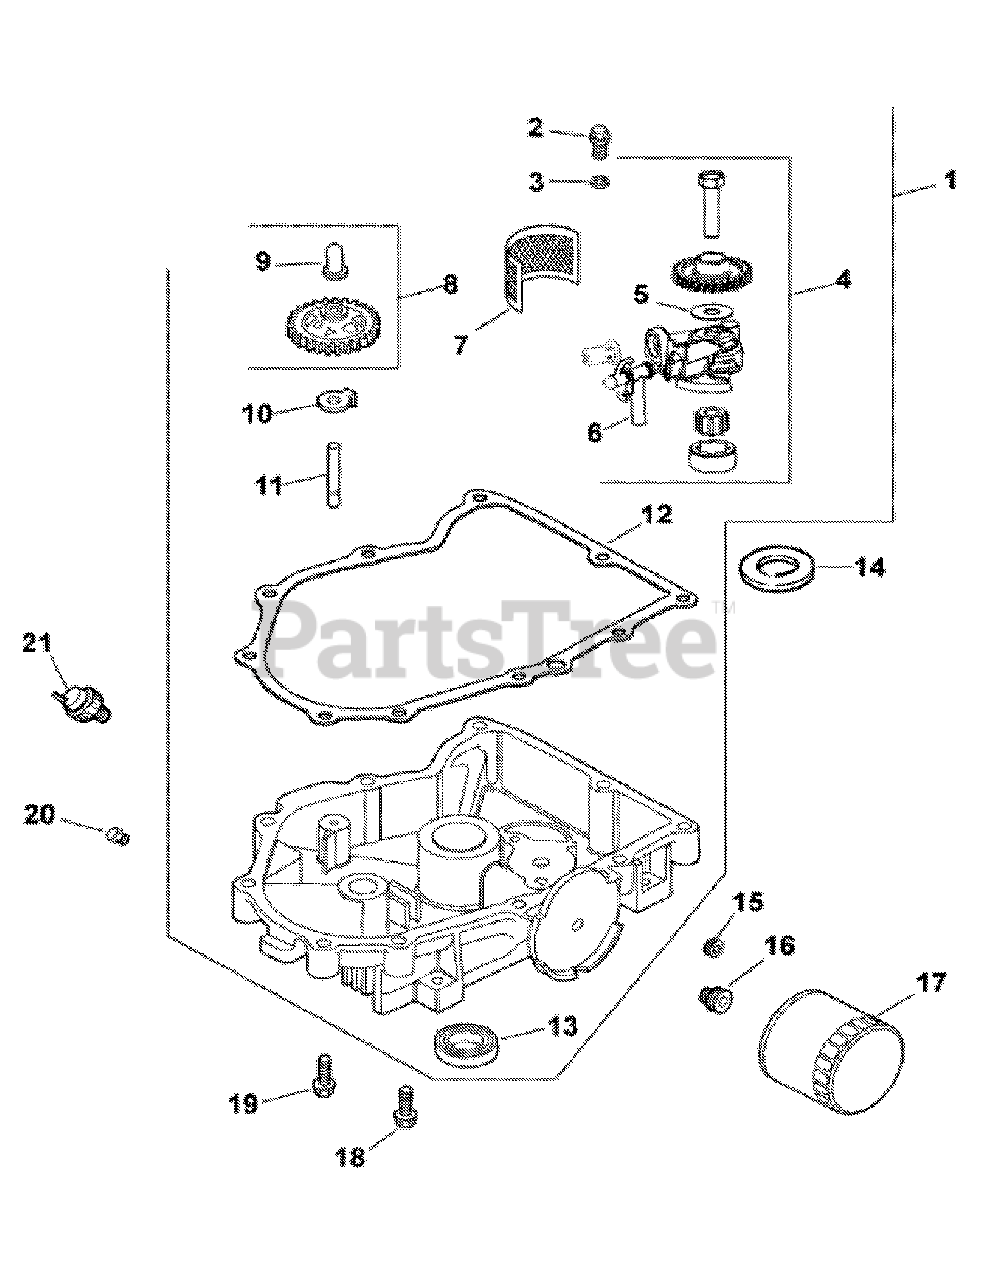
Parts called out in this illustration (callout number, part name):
1	Oil Pan Kit w/Gasket
2	Hex Flange Screw
3	Plain Washer
4	Oil Pump Assembly
6	Oil Pick-Up Tube
8	Governor Gear Kit
9	Governor Regulating Pin
11	Governor Gear Shaft
12	Oil Pan Gasket
13	Oil Seal (PTO End)
16	Oil Filter Nipple
17	Oil Filter
18	Hex Flange Screw
19	Hex Flange Screw
21	Oil Pressure Switch
